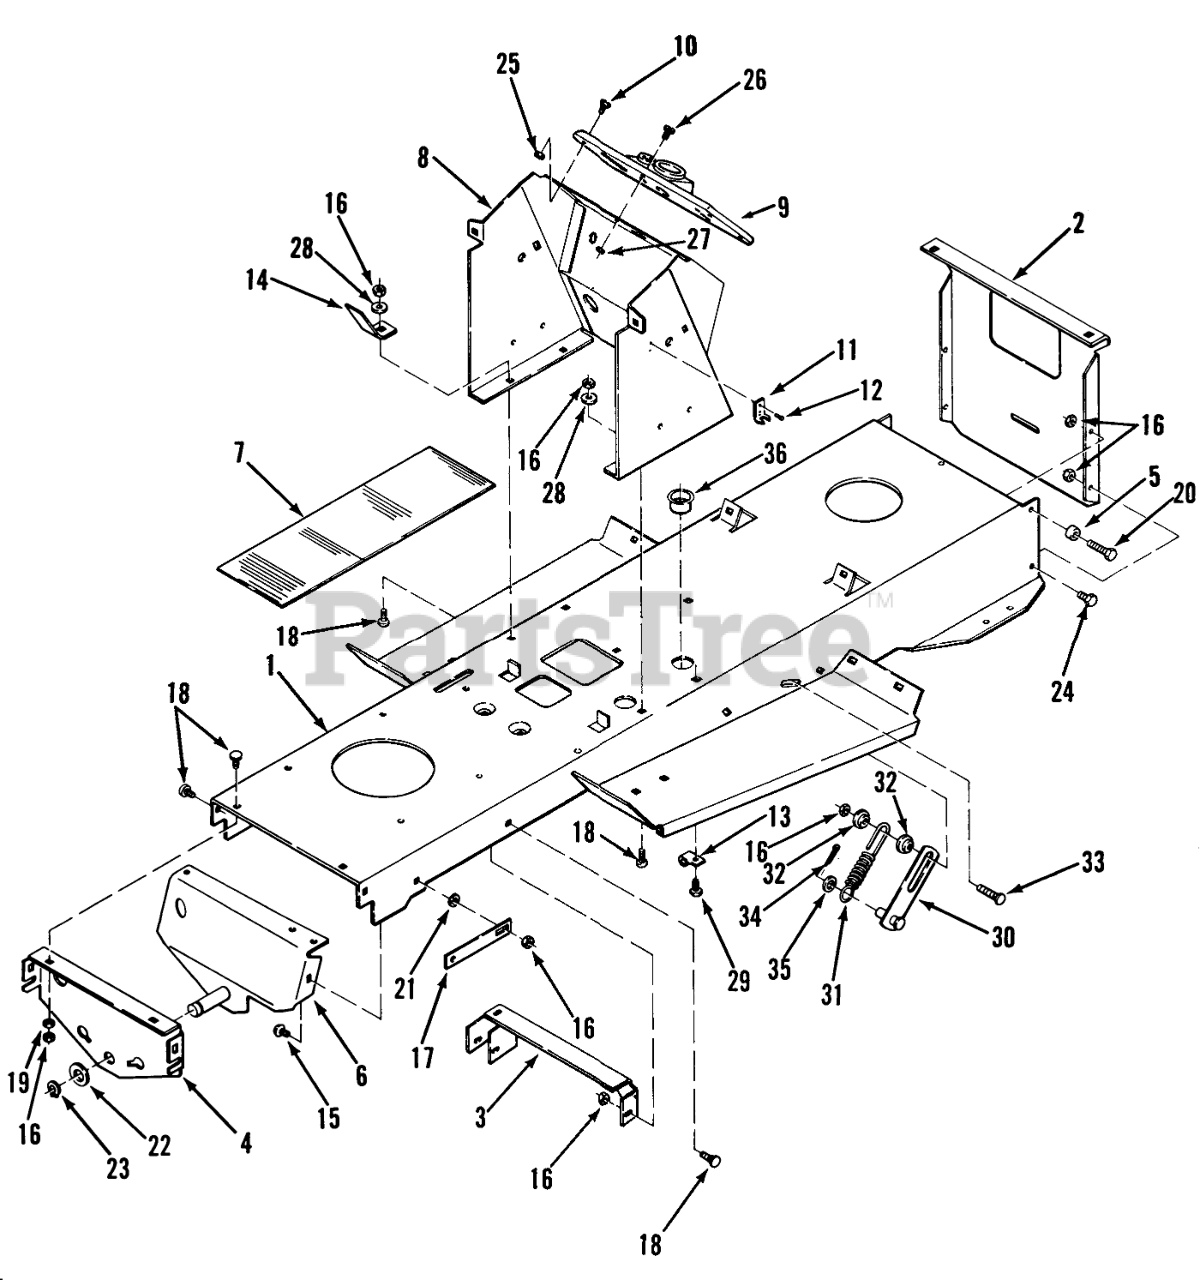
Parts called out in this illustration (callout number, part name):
1	Frame
2	PLATE DRAWBAR
3	Frame Support Plate
4	PLATE SUPT - AXLE R
5	Spacer
6	REAR AXLE SUPPORT ASSY R
7	PAD-FOOTREST
8	HOODSTAND ASSY
8	Hoodstand 211-5
9	CONSOLE
10	SCREW #10X.62 PHCR
11	ASSY-FLEX DRAW LATCH
12	RIVET
13	J-CLIP
14	BRACKET FUSE
15	Bolt-Carriage
16	Nut
17	STRAP R
18	Bolt
19	LOCKWASHER
20	Bolt
21	Washer-Lock
22	WASHER
23	Snap Ring
24	Bolt
25	Nut
26	Screw
27	Nut
28	Washer
29	Bolt
30	ASSY LINK B
31	SPRING
32	BUSHING
33	Bolt-Carriage
35	WASHER
36	BUSHING-NYLON 1.093
